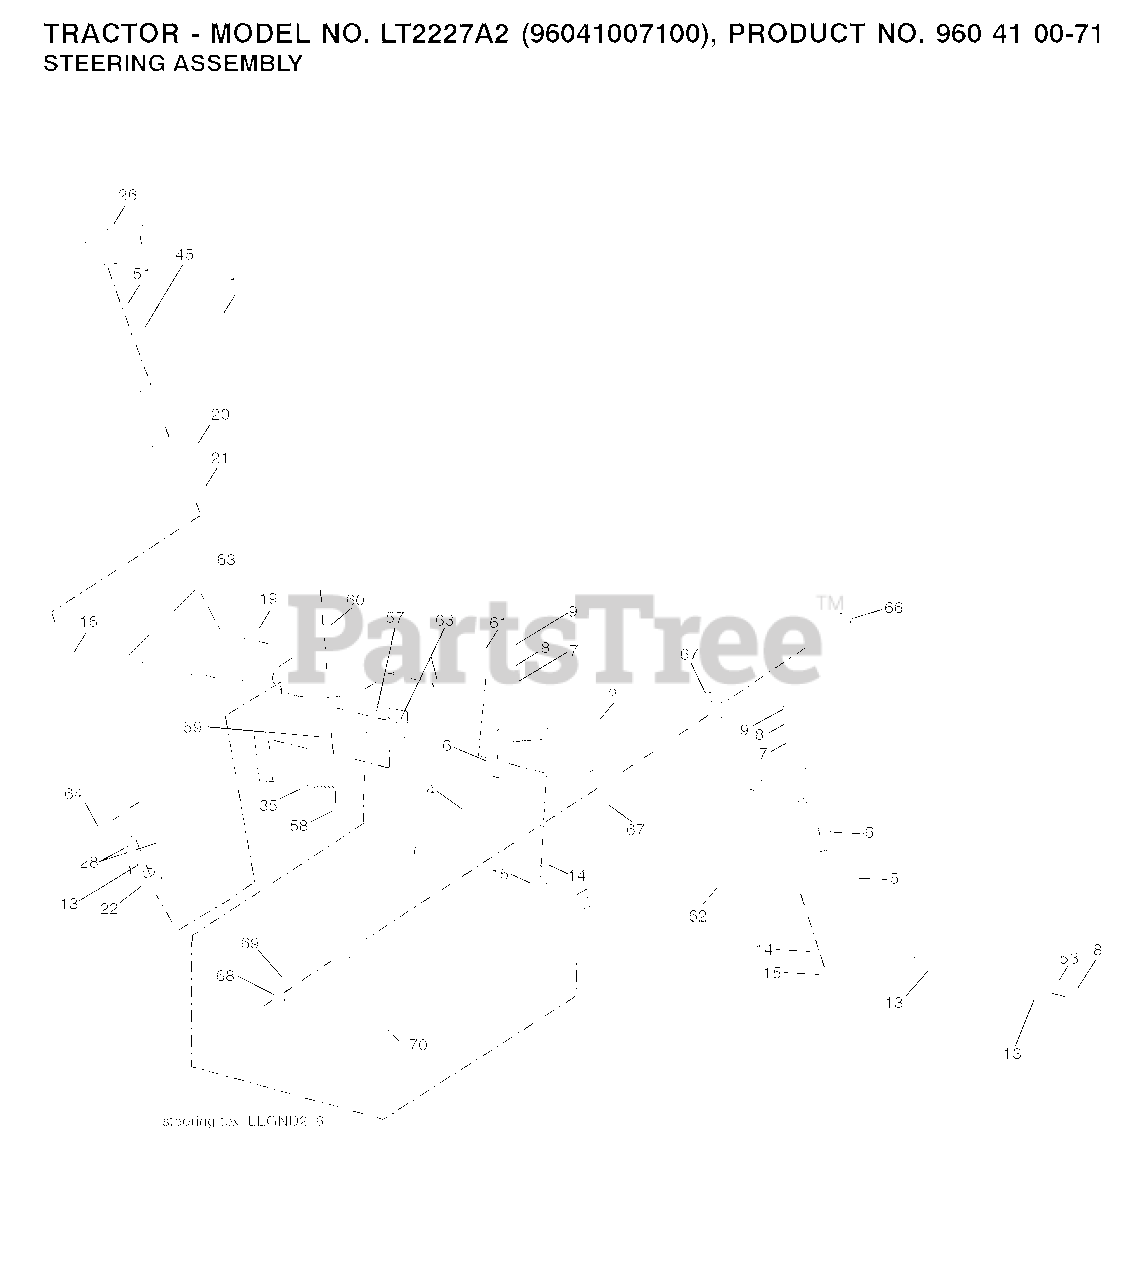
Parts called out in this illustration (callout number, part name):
1	WHEEL.STEERING.PREM.2.BLK
2	AXLE.CAST.IRON
4	SPINDLE.WELDED.LH.16"TEX
5	SPINDLE.WELDED.RH.16"TEX
8	RING CLIP
9	CAP.SPINDLE
14	WASHER, LOCK 3/8
15	NUT CROWNLOCK 3/8-24
16	SHAFT.STEER.STEALTH.DD
19	PLATE.STEER.DDL.NLT/NG
20	BOOT.STEERING.
21	ADAPTER, WHEEL STNG..
22	BUSHING.ASM.STEERING.A
26	INSERT.CAP.STRG.WH.BLACK
28	SCREW, 3/8-16X3/4
35	GEAR.SECTOR.PLATE.DDL.
45	WASHER 9/16"ID, 2 3/8"OD
51	NUT.HEX.1/2-20
53	WASHER.HARDENED
57	BRKT.UPSTOP.GT/LT.TEX
58	BOLT.SHOULDER.SECTOR.P
59	WASHER.THURST.SECTOR.S
60	NUT FLANGE LOCK 5/8-11
61	DRAGLINK.LH.BALLSTUD.D
62	DRAGLINK.RH.BALLSTUD.D
63	SCREW
64	RETAINER.CLIP.SPRING.S
66	BOLT HEX FGHD 7/16-14 X 3 SERR
67	BUSHING.PM.FRONT AXLE
68	NUT.LOCK.FLANGE.7/16
69	WASHER.1.5X.505X.118
70	BRKT.DECK.SUSPENSION.F
